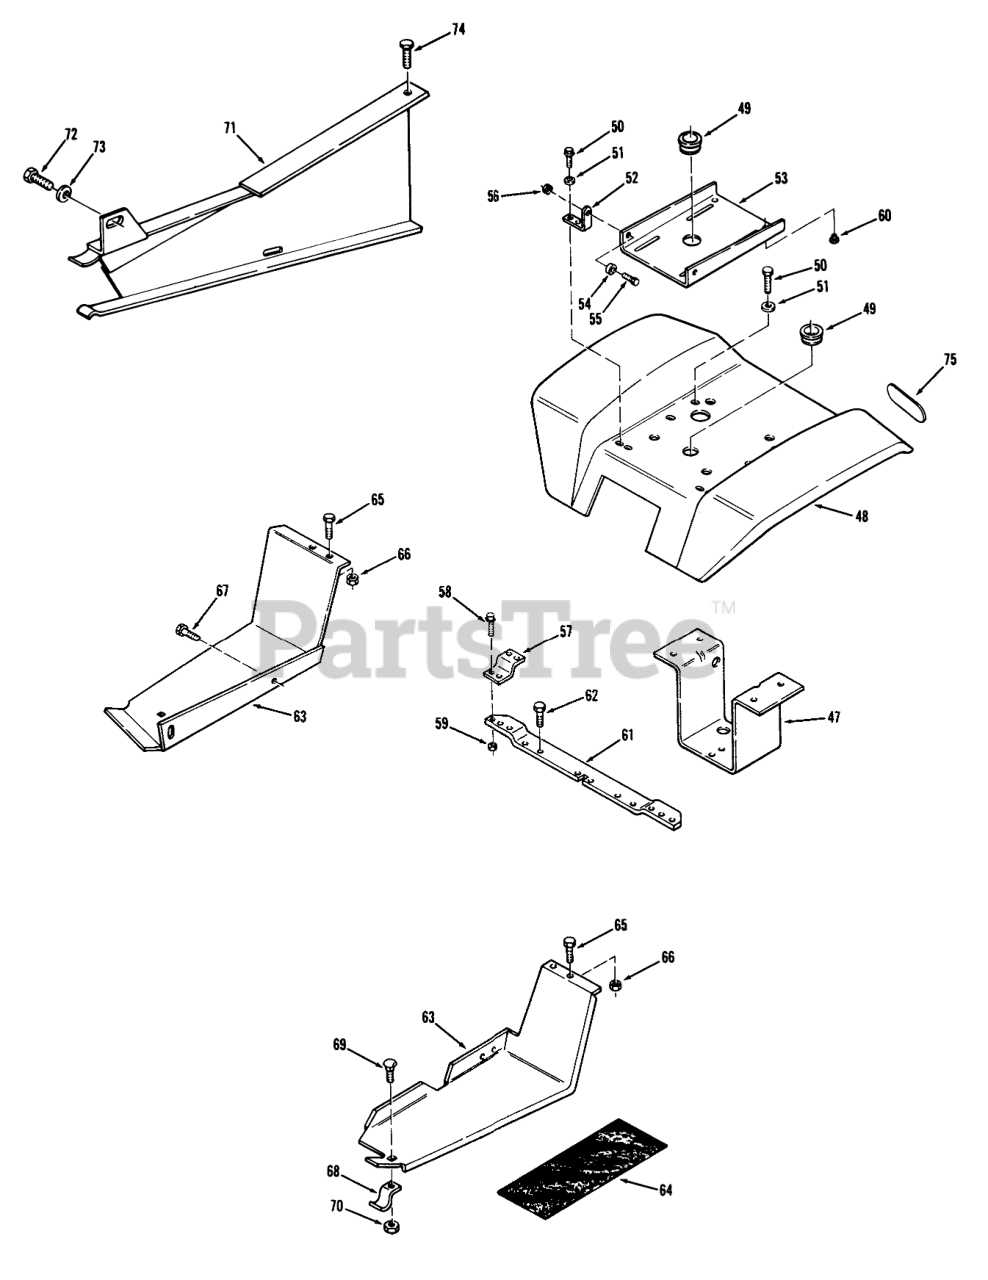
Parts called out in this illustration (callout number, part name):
47	Bracket-Fender
48	Fender
49	Bushing
50	Bolt
51	WASHER 5/16 SAE
52	BRACKET-PIVOT
53	Plate Seat Pivot
54	BUSHING
55	HHCS
56	Nut
57	BRACKET-FENDER R
58	HHCS
59	Nut
60	BUMPER-RUBBER
61	Bracket-Footrest
62	SCREW
63	Footrest-RH
63	Footrest-LH
64	PAD-FOOTREST
65	Bolt
66	Nut
67	Screw
68	BRACKET
69	Bolt
70	Nut
71	Belt Guard Assy
72	H H C S
72	Bolt
73	LOCKWASHER
74	Screw
75	Reflector
